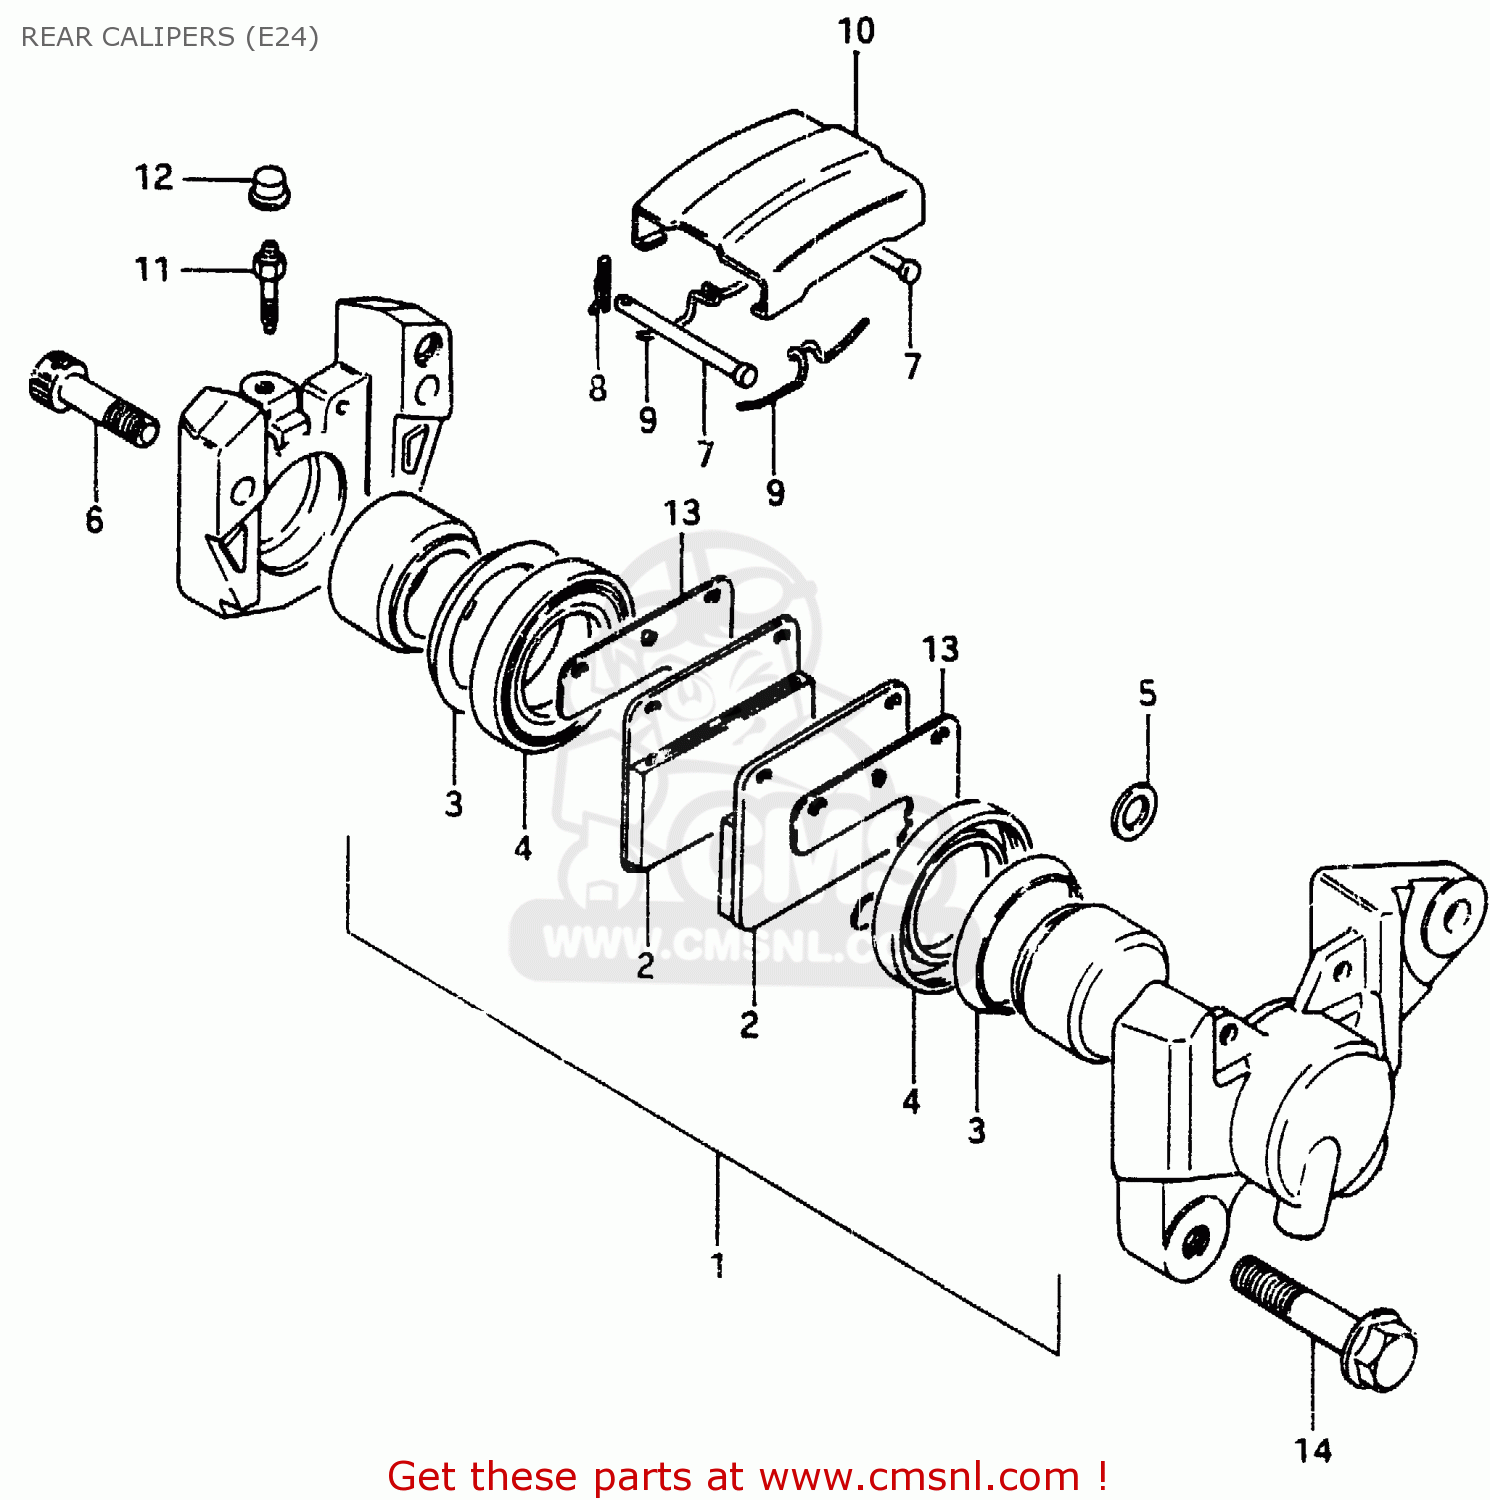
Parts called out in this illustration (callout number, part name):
1	PISTON SET
2	PAD,BRAKE (MCA)
3	SEAL,PISTON
4	BOOT,PISTON
5	SEAL,JOINT
6	BOLT,CALIPER HOUSING
7	PIN,PAD
8	CLIP,PAD PIN
9	SPRING
10	COVER,DUST
11	BLEEDER
12	CAP,BREATHER
13	SHIM,RR CALIPER
14	BOLT 10X30
